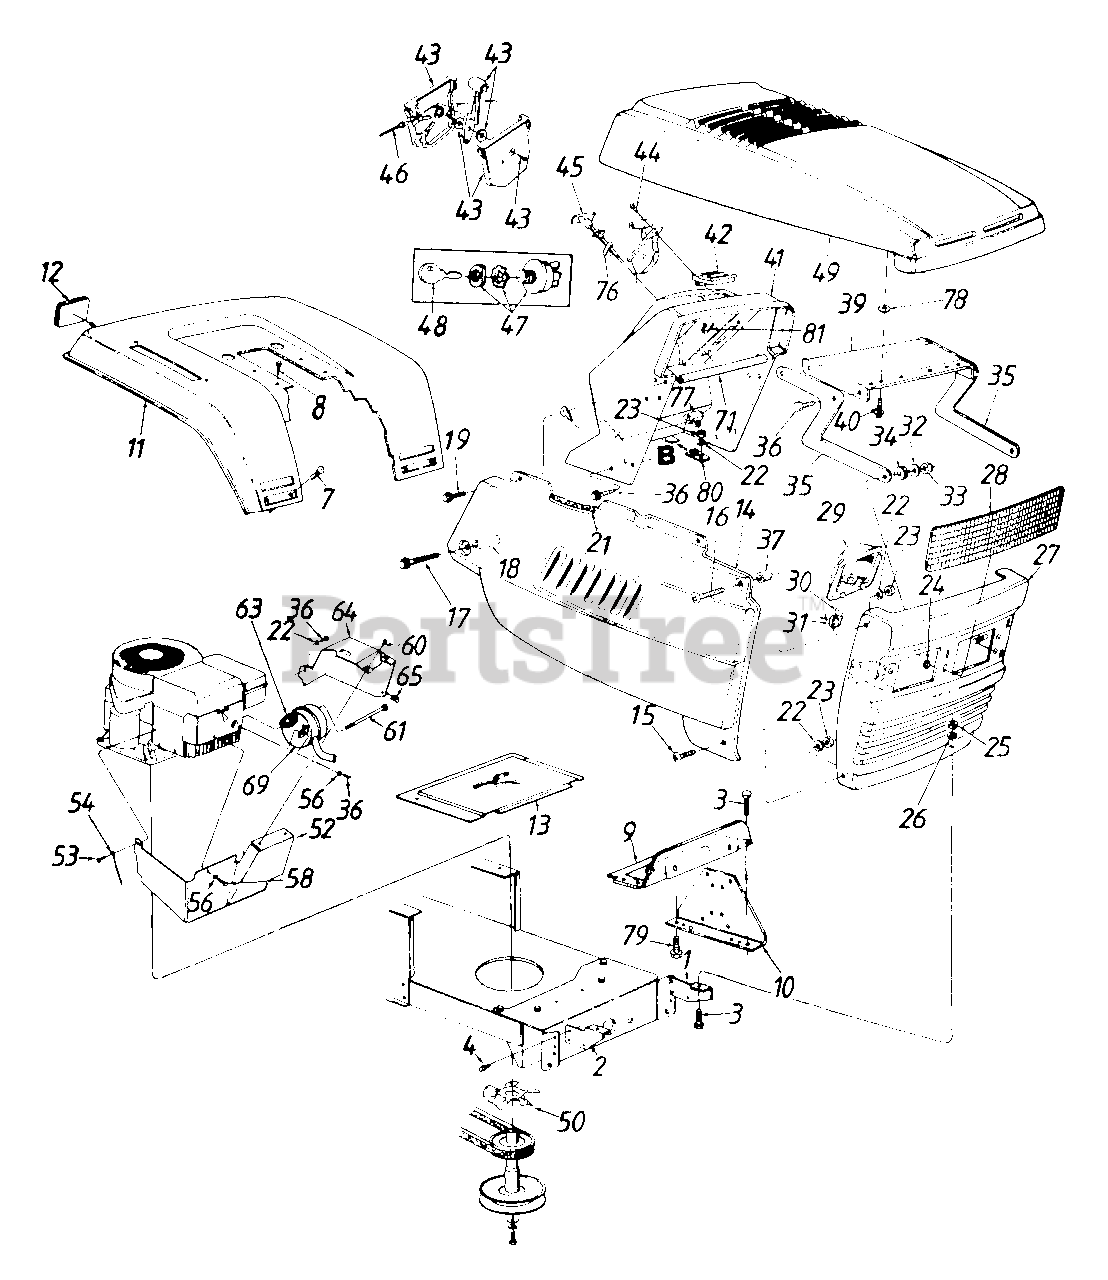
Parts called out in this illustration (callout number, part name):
1	Grille Mtg. Brkt.- L.H.
4	Hex Wash. Hd. Tap Scr. 5/16-18 x .5" I g.
7	Carriage Bolt 1/4-20 x .5" Lg.
8	Hex Wash. Hd. Tap Scr. 5/16 x .75" Lg.
16	Truss Mach. Scr. 1/4-20 x 1.0" Lg.
17	Hex Wash. TT-Tap Scr. 1/4-20 x 1.75" Lg.
18	Spacer .26" I.D. x 1.32"
19	Hex Rolling Tap Scr. 1/4-20 x .75" Lg.
21	Trim Strip - 12" Lg.
22	L-Wash. 1/4" I.D.
23	Hex Nut 1/4-20 Thd.
24	Speed Nut 5/16" Thd.
25	Hex Nut 5/16-18 Thd.
26	Fl-Wash. .344" I.D. x 1" O.D.
29	Headlamp Housing
30	Headlamp
31	Twist Lock Lamp Socket
32	Bell-Wash. .345" I.D. x .88"
33	Hex L-Nut 5/16-18 Thd.
34	Rubber Washer
35	Hood Hinge
36	Hex Wash. Hd. B-Tap Scr. 1/4-20 x .5" Lg.
37	Spacer .262" I.D. x .31"
41	Dash
42	Ammeter
43	Throttle Control Box Ass'y.
44	Mach. Scr. #10 x .44" Lg.
45	Choke Control 23" Lg.
46	Throttle Control Wire 18.5" Lg.
47	Ignition Switch
48	Ignition Key
52	Muffler Heat Shield - Front
53	Truss Mach. Scr. 5/16-18 x .75" Lg.
54	Ground Wire
56	Spr. Wash. 1/4" I.D.
58	Hex Bolt 1/4-20 x 3/8" Lg.
60	Hex B-Tap Scr. #10 x .38" Lg.
61	Shoulder Bolt
63	Exhaust Gasket
64	Muffler Heat Shield - L.H.
65	Speed Nut #10-24 Thd.
69	Muffler
71	Grille Support Tube
76	Choke Retainer
77	Light Switch
78	Fl-Wash. .406" I.D. x .812" O.D.
79	Hex Bolt 1/4-20 x .62" L.g.
80	Dash Fastening Tab
81	Cable Tie
